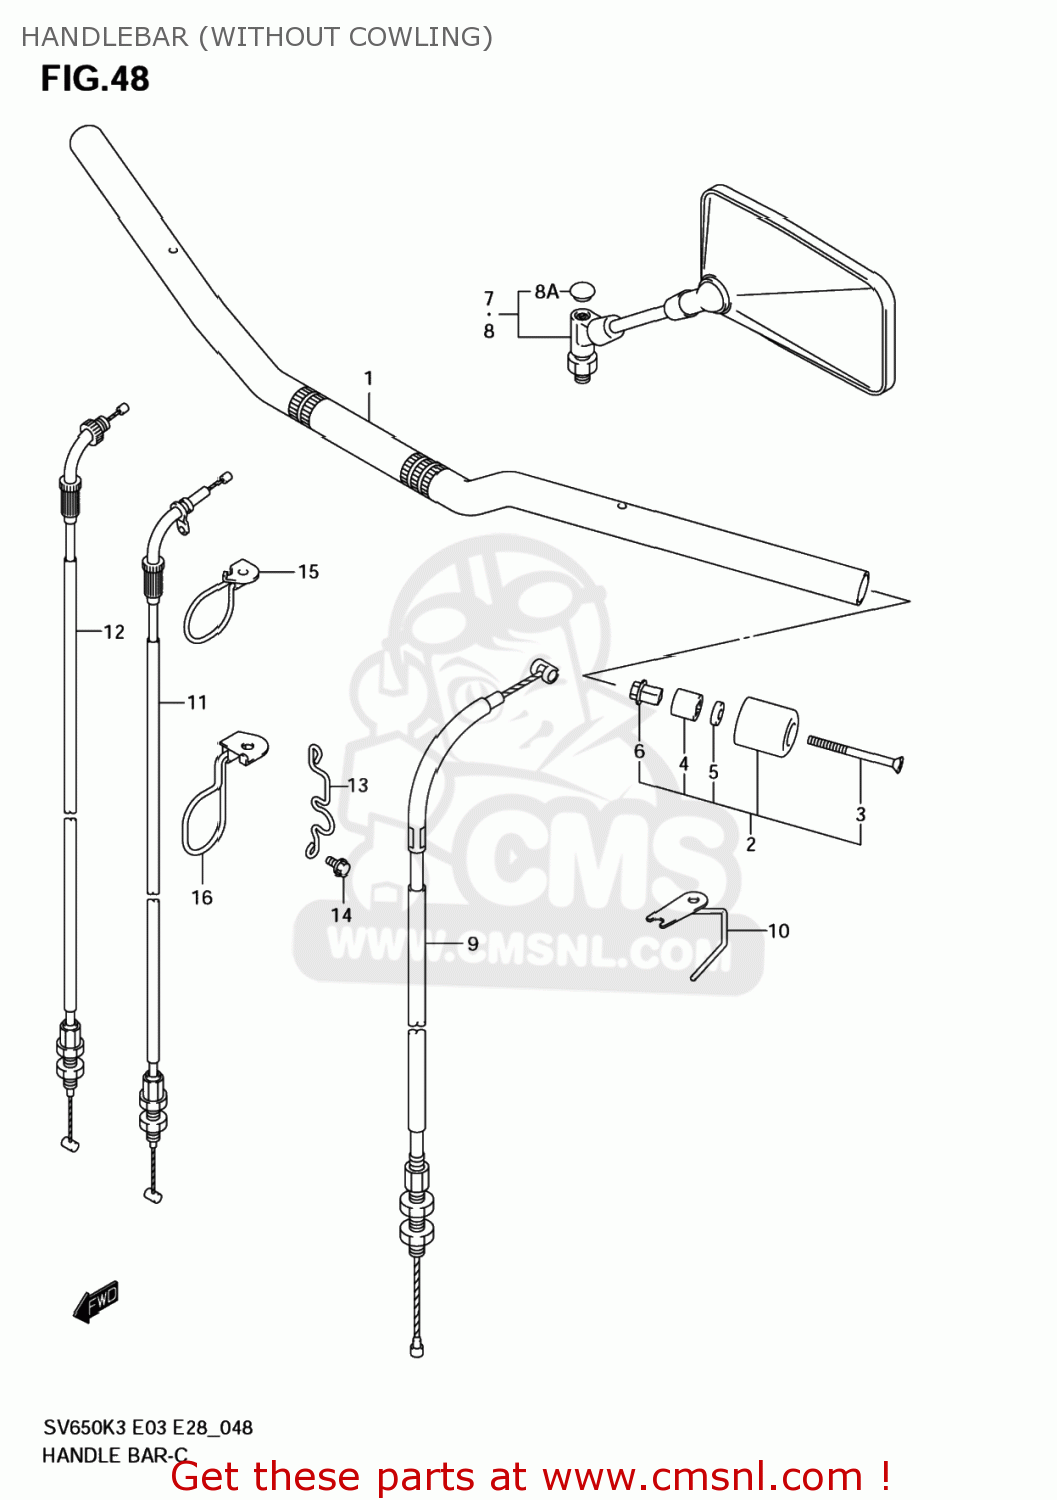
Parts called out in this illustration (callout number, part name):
1	HANDLEBAR
2	BALANCER,HANDL
3	SCREW
4	EXPANDER,HANDLE BALANCER
5	WASHER(6.5X16X4)
6	NUT,HANDLE BAL
7	MIRROR ASSY,RE
8	MIRROR ASSY,RE
8A	CAP
9	CABLE ASSY,CLUTCH
10	GUIDE,CLUTCH CABLE
11	CABLE ASSY,THROTTLE NO.1
12	CABLE ASSY,THROTTLE NO.2
13	GUIDE,CABLE L
14	BOLT
15	GUIDE,THROTTLE CABLE
16	GUIDE,THROTTLE CABLE NO.2
